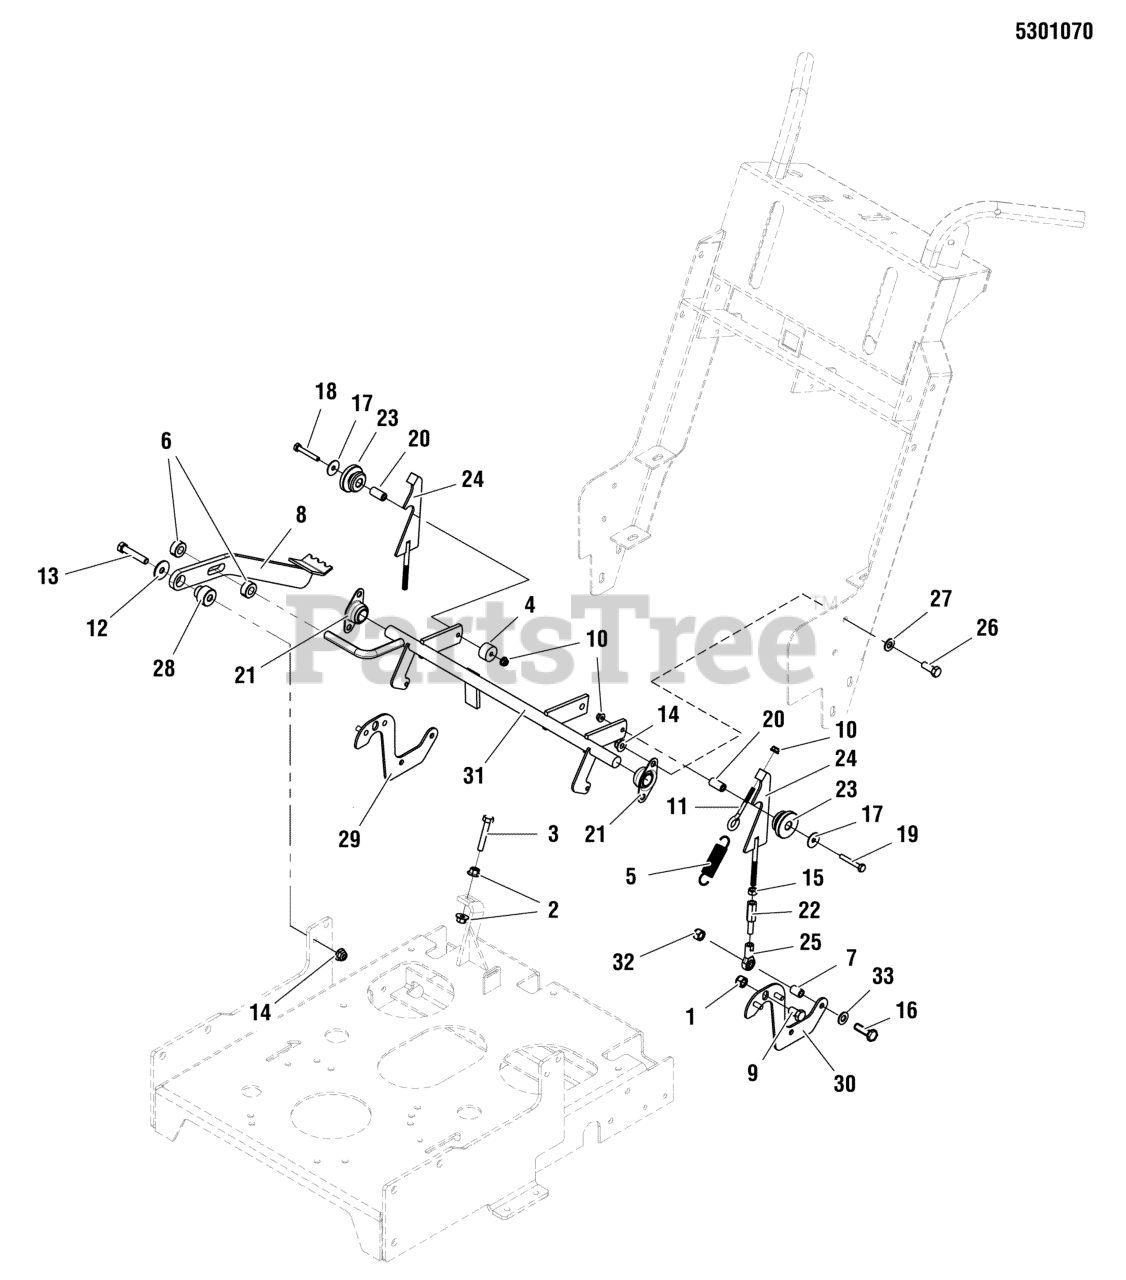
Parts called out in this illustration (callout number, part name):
1	NUT, 7/16-14 HEX TOP LOCK
2	NUT, .31-24 HEX FLG SERRATED LK
3	BOLT, 5/16-24 X 1-3/4, FULL THRD, GD5 YZ
4	SPACER, .26 X .50 X .50 YZ
5	SPRING, EXTENSION, 3.281 X .751 X .075 WIRE
6	COLLAR, 1/2 SET (1/2 SPLIT COLLAR IN MODEL)
7	SPACER, .33 X .63 X 1.00, YZ
8	WELD, FOOT PEDAL, SW30 - RED
9	BOLT, 7/16-14 X 3/4, GD 5 YZ
10	NUT, 1/4-20 Hex Nylock Flange
11	EYE BOLT, 1/4-20 X 3, ZC
12	WASHER, .390 X 1.50 X .109, YZ
13	BOLT, 3/8-16 X 2, GD5, CZ
14	NUT, 3/8 - 16 HEX NYLOCK FLANGE
15	NUT, 5/16-24 HEX, LH
16	* BOLT, 5/16-18 X 2-1/4 GD5 YZ
17	WASHER, 1/4" Fender
18	BOLT, 1/4-20 X 2-1/4 GD5 CZ
19	BOLT, 1/4 X 20 X 1-3/4 GD5 YZ
20	SPACER, .251 X .5005 X .860, BRASS
21	BEARING, BRONZE FLANGE, 3/4"
22	ADJUSTER, ROD LINKAGE 5/16-24
23	ROLLER, SPEED CONTROL
24	ROD, CONTROL RAMP
25	BALL JOINT 5/16-24 RH FEMALE STAMPED STL
26	BOLT, 3/8-16 X 1" GD5 CZ
27	WASHER, 3/8 SAE
28	SPACER, .38 X 1.13 X 1.00 STEP, YZ
29	WELD, CONTROL ARM - RH - RED
30	WELD, CONTROL ARM - LH - RED
31	WELD, CONTROL SHAFT - RED
32	NUT, 5/16-18 HEX NYLOCK FLANGE NUT
33	WASHER, 5/16" SAE
